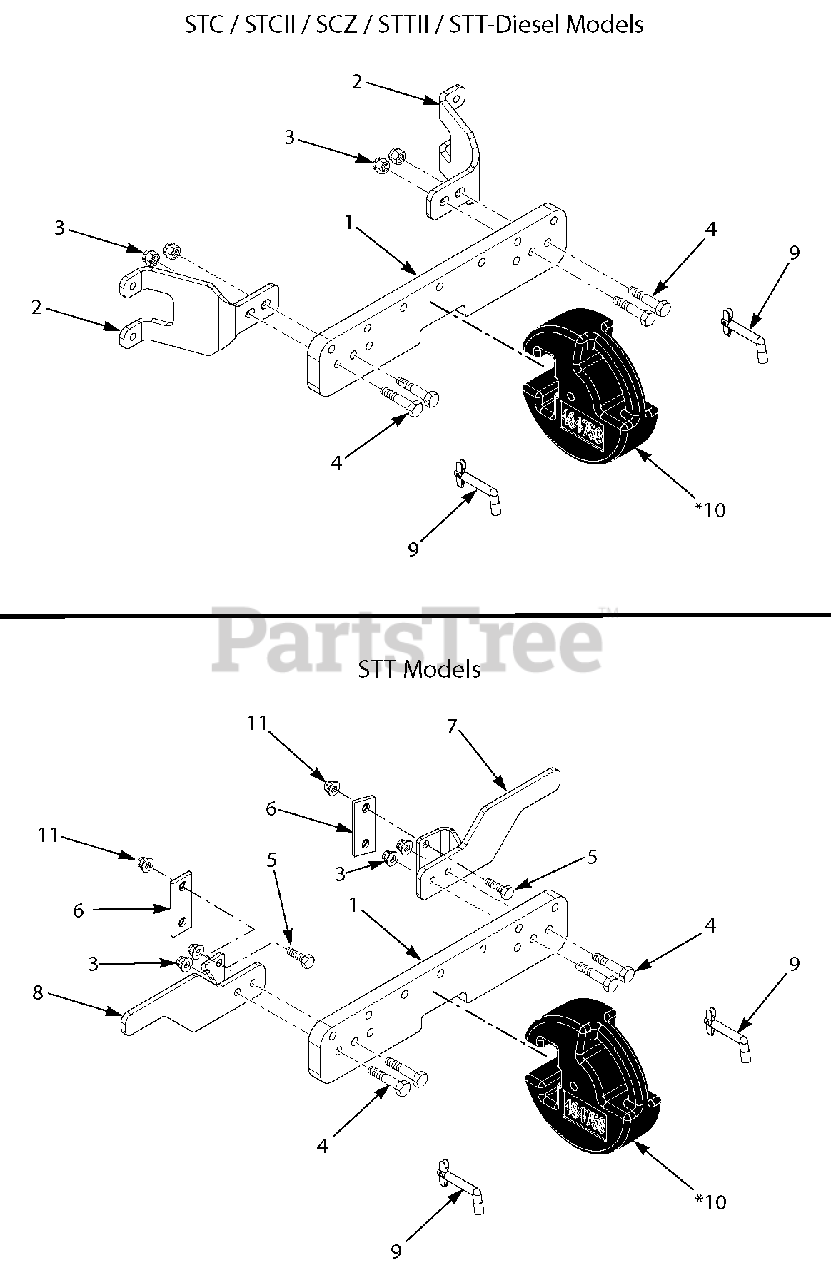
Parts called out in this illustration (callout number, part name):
1	Weight Bar
2	Bracket, LH Weight Bar (STC / STCII & SCZ48/52)
2	Bracket, RH Weight Bar (STC / STCII & SCZ48/52)
2	Bracket, Weight Bar (LH & RH for STT-Diesel, STTII52/61 & SCZ61)
3	Nut, Elastic Flange 1/2-13
4	Bolt, Hex Head 1/2-13
9	Pin, Weight Retention
10	Weight (see below)
